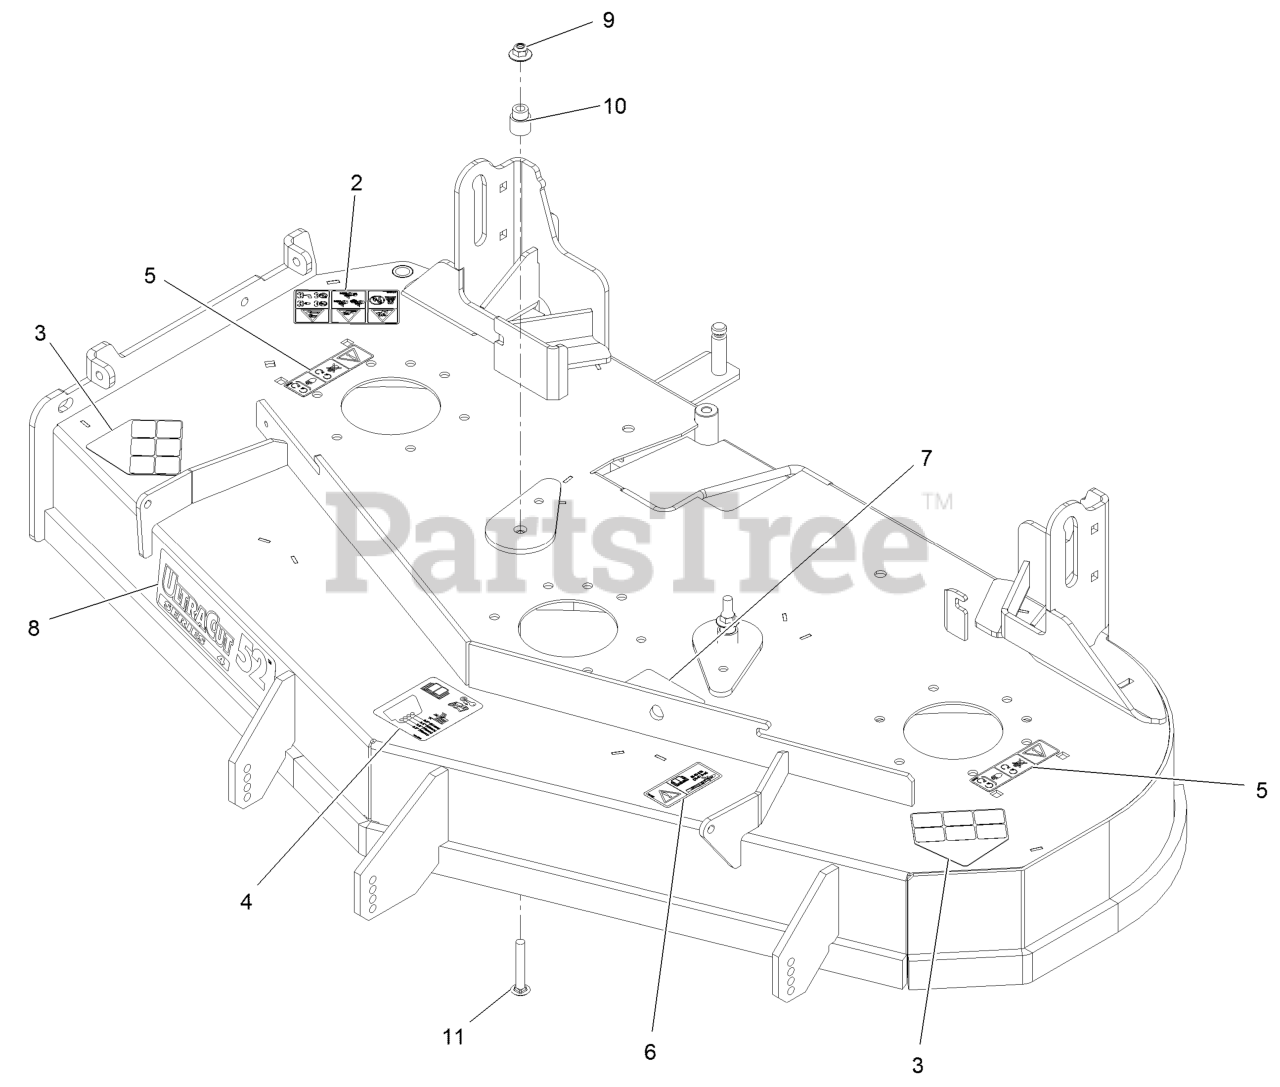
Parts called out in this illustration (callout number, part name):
2	DECAL-DANGER
3	DECAL-DANGER
4	DECAL-ROLLER, ANTI-SCALP
5	DECAL-COVER, MISSING
6	DECAL-BOLT TORQUE
7	DECAL-BELT ROUTING
8	DECAL,ULTRACUT 52 SERIES
9	Nut-Nyloc 3/8-16 Flg
10	BUSHING-IDLER
11	SCREW-CARR
